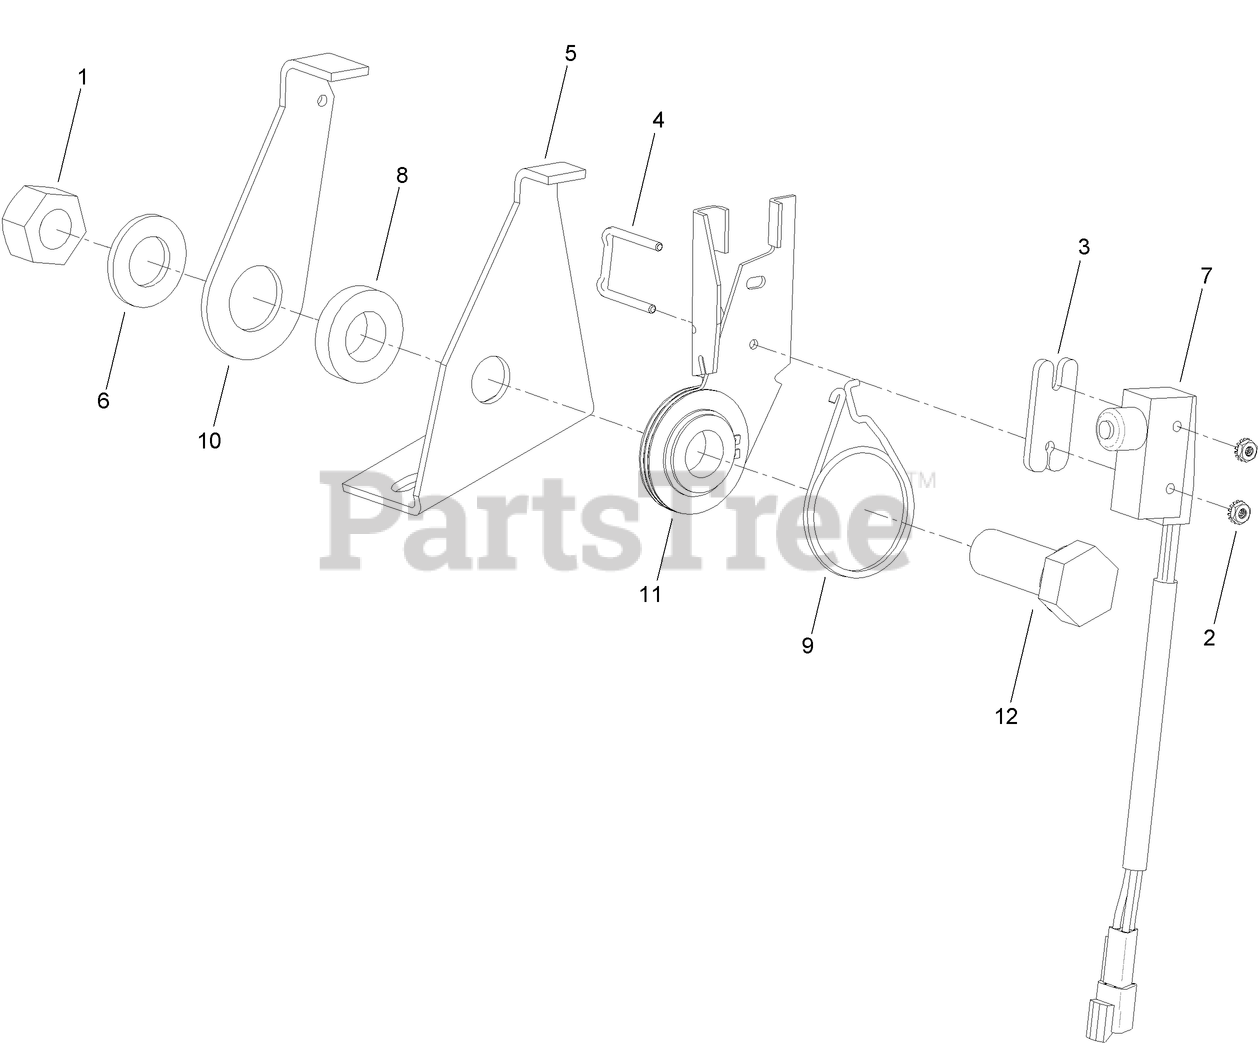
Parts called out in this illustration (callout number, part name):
1	NUT-LOCK
2	NUT-KEPS
3	SPACER-SWITCH
4	BOLT-U, SWITCH MTG (H435814)
5	PLATE-MOUNTING
6	WASHER-FLAT
7	SWITCH-NEUTRAL START
8	HUB-ACTUATOR
9	SPRING-CENTERING
10	PLATE-ACTUATOR
11	NEUTRAL SWITCH MOUNTING ASM
